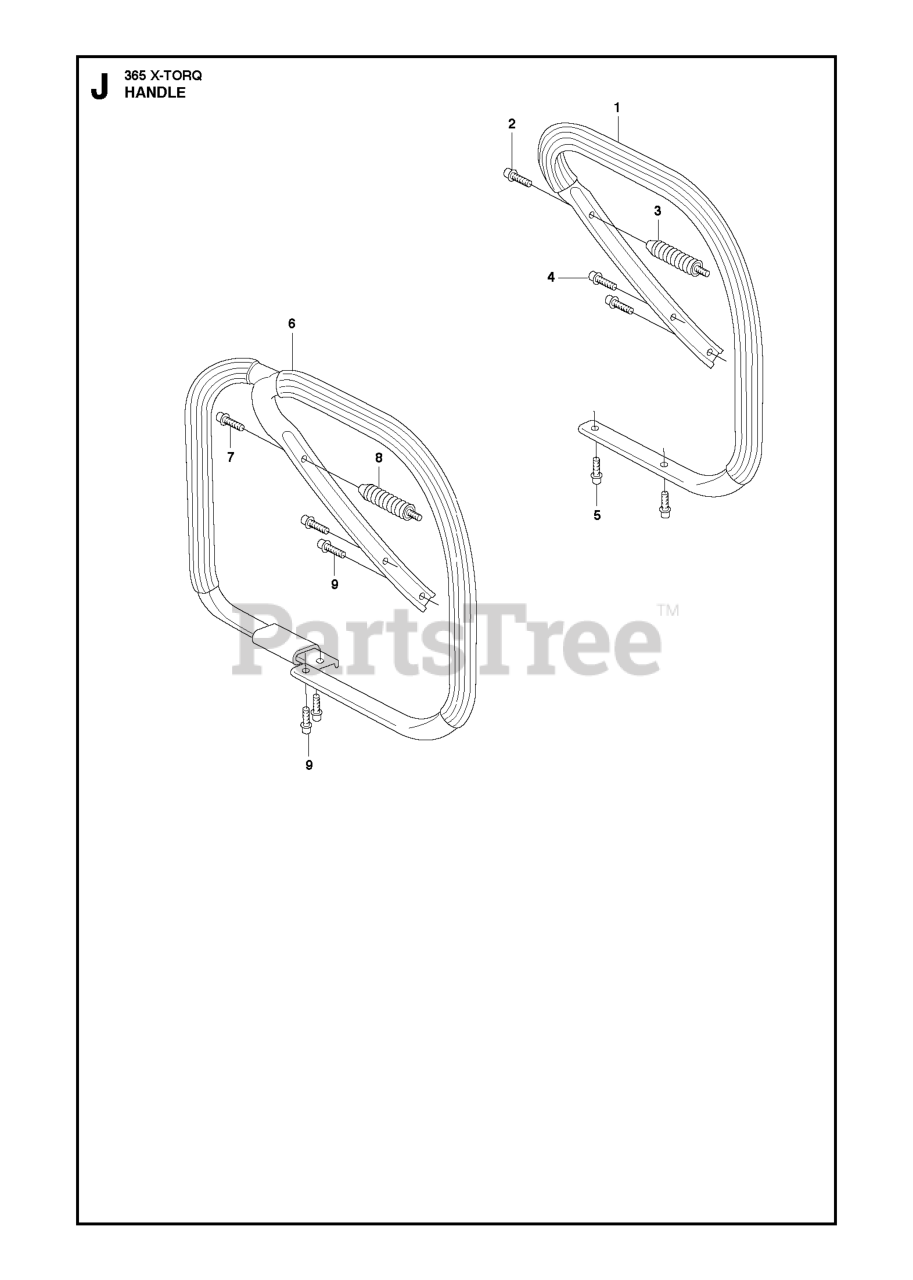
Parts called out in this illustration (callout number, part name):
1	FRONT HANDLE ASSY
2	SCREW ITXSCFT PW6.3X22 T27 8.
3	VIBRATION ISOLATOR
3	ANTIVIBRATION ELEMENT
4	SCREW ITXSCFT PW5.5X16 T27 8.
5	SCREW ITXSCFT PW5.5X16 T27 8.
6	FRONT HANDLE ASSY
7	SCREW ITXSCFT PW6.3X22 T27 8.
8	VIBRATION ISOLATOR
9	SCREW ITXSCFT PW5.5X16 T27 8.
